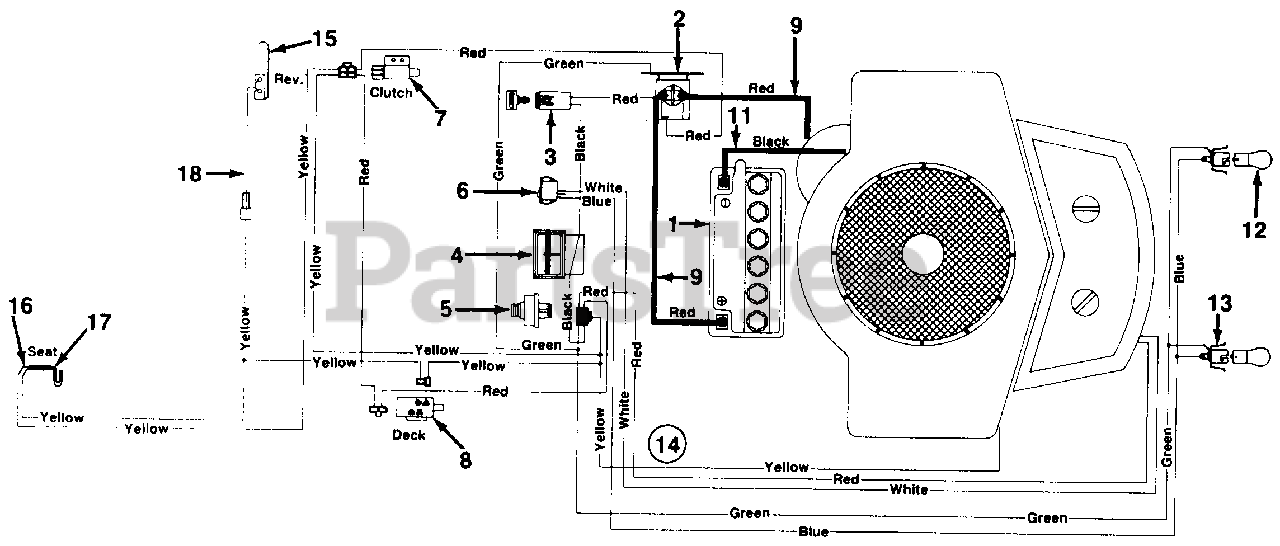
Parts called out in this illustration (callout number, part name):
1	Battery (275 Cold Crank Amps)
2	Solenoid
3	Fuse 7.5 Amp
4	Ammeter
5	Ignition Switch
6	Light Switch
7	Safety Switch (Clutch)
8	Safety Switch (PTO)
9	Electric Wire 14" Lg.
11	Ground Wire 7.5" Lg.
12	Lamp
13	Socket
14	Wire Harness w/Ammeter
15	Spring Switch (Reverse)
16	Spring Switch (Seat)
17	Spring Switch (Seat)
18	Ext. Wire
